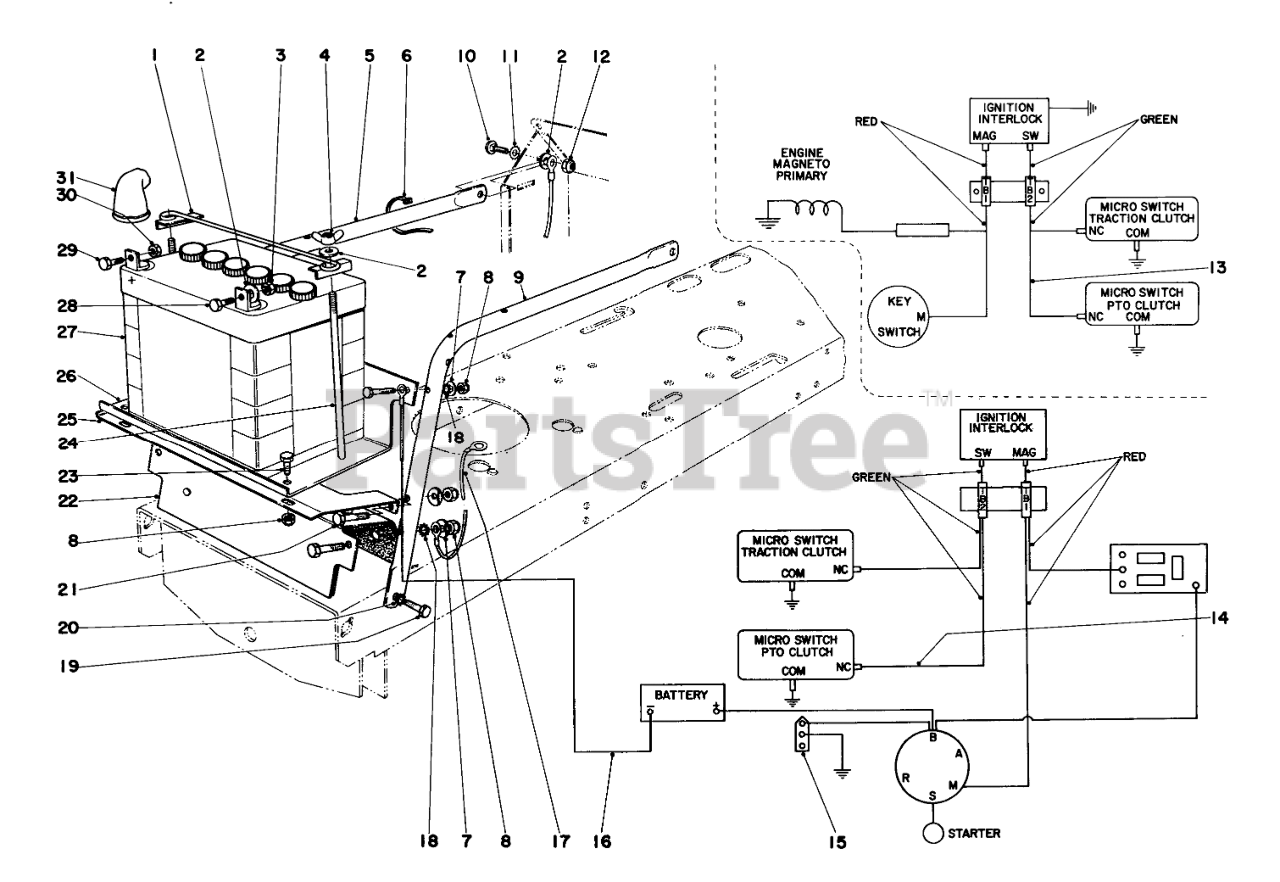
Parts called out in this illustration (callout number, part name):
1	Clamp
2	WASHER-FLAT
3	NUT-HEX
4	WING NUT
5	Support Gas Tank, Right
6	Cable Tie
7	WASHER
8	NUT-LOCK, CONE
9	Support Gas Tank, Left
10	SCREW-CARRIAGE
11	WASHER-LOCK/EXT
12	NUT-LOCK
13	Wire Harness (Model 57131)
14	Wire Harness (Model 57228)
15	Socket Assembly (Model 57228)
16	Wire Assembly (Model 57228)
17	ENG-GROUND WIRE ASM
18	WASHER-LOCK/EXT
19	SCREW-HH
20	WASHER-LOCK
21	SCREW-HH
22	Heat Shield
23	SCREW-HH
24	BATTERY BOLT
25	Brace Battery Shelf (Model 57228)
26	Shelf, Battery (Model 57228)
27	Battery
28	SCREW-HH
29	SCREW-HH
30	NUT-HEX
31	BATTERY BOOT
